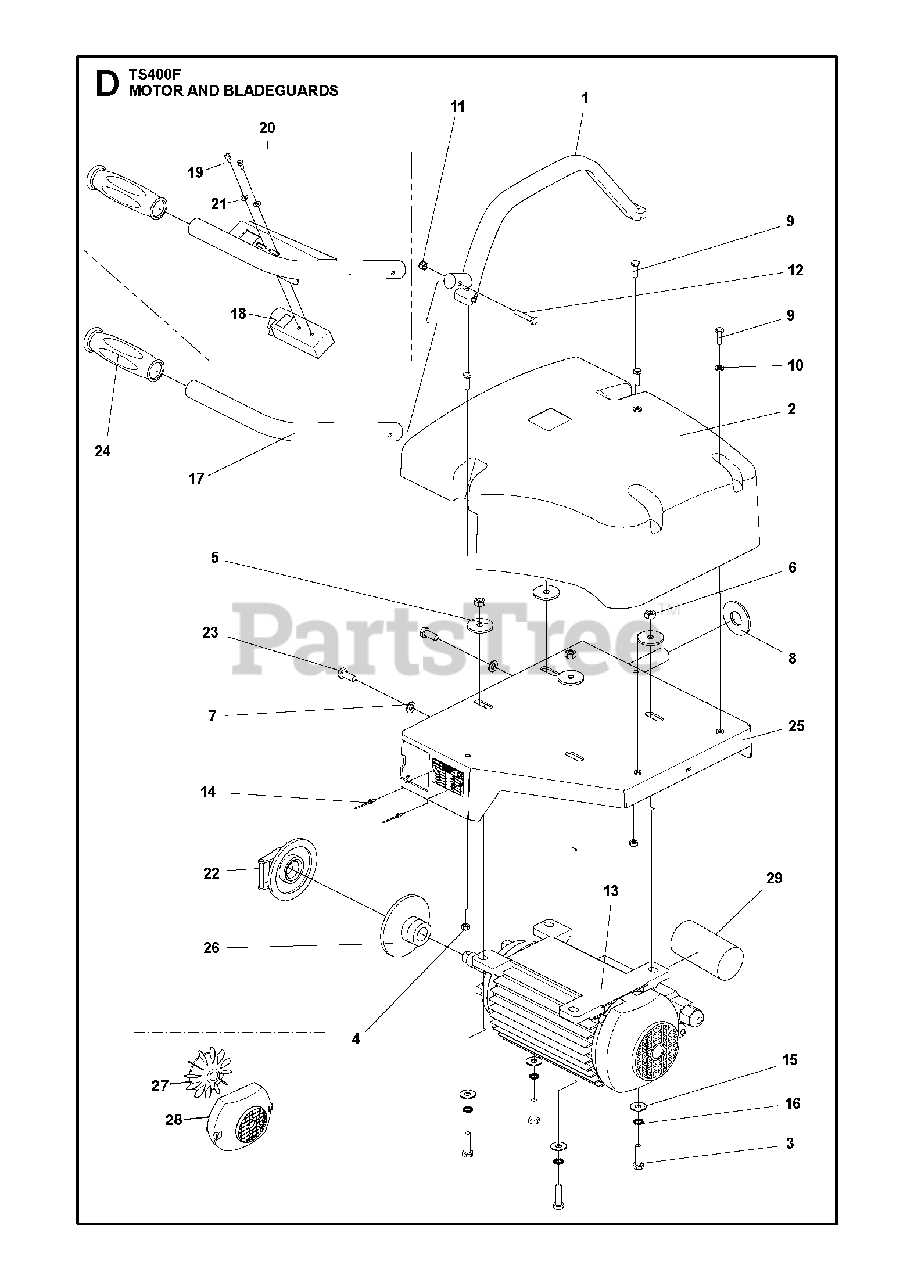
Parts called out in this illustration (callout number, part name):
6	HEXAGON NUT
7	WASHER
11	HEXAGON LOCKING NUT
15	RONDELLE ACIER L8 BICHRO/
20	HANDLE KITUntil s/n 2015 3200019
29	CAPACITOR"230V ""Capacitor 35_F for 2.2Kw motor"""
29	CAPACITOR"110V ""Capacitor 25_F for 1.1Kw motor"
